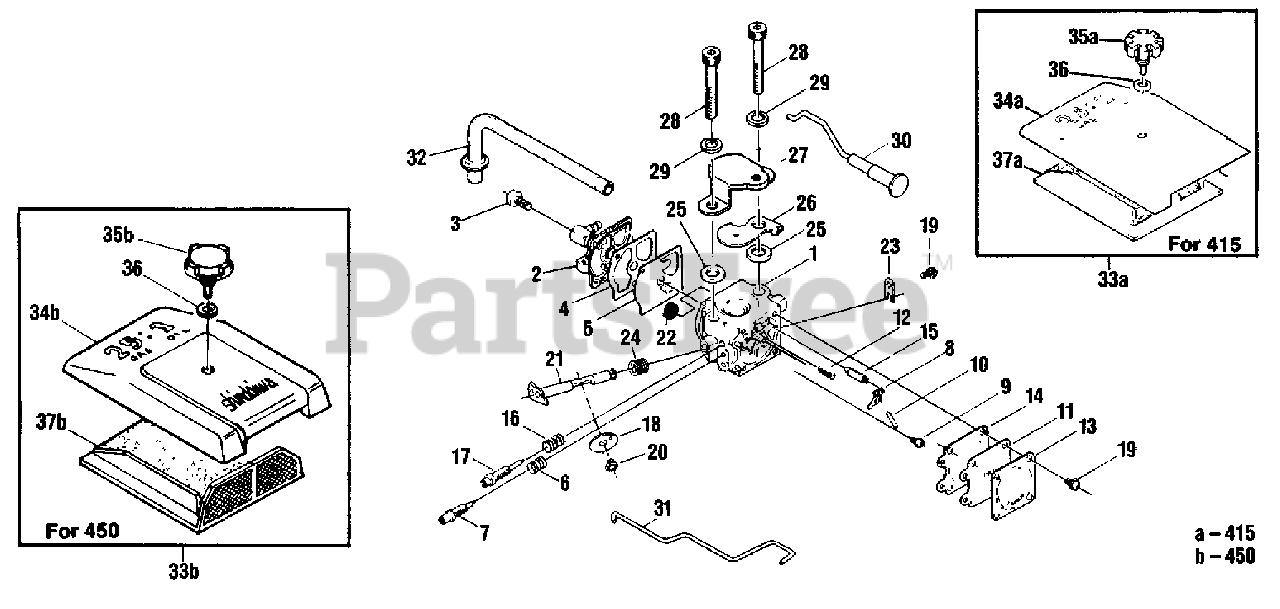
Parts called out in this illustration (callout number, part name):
1	BASE, PURGE
2	PUMP COVER ASSY
3	SCREW, PUMP COVER
4	GASKET, PUMP
5	DIAPHRAGM, PUMP
6	SPRING
7	NEEDLE - LOW SPEED
8	LEVER, METERING
9	SCREW, METERING LEVER PIN
10	PIN, METERING LEVER
11	DIAPHRAGM, METERING
12	SPRING, METERING LEVER
13	DIAPHRAGM, METERING
14	GASKET, METERING
15	VALVE, INLET NEEDLE
16	SPRING
17	NEEDLE - HIGH SPEED
18	VALVE, THROTTLE
19	SCREW
20	SCREW
21	SHAFT
22	STRAINER
23	RING, RETAINING
24	SPRING, RETURN
25	WASHER
26	PLATE, SHUTTER
28	SCREW - 5X40
29	LOCKWASHER - 5
30	ROD, CHOKE
31	ROD, THROTTLE
32	PIPE - IMPULSE
33A	AIR FILTER COVER ASSY
33B	AIR FILTER COVER ASSY
34A	COVER, AIR FILTER
34B	COVER, AIR FILTER
35A	THUMBSCREW
35B	THUMBSCREW
36	O-RING
37A	FILTER, AIR - FLOCKED
37B	FILTER, AIR - FLOCKED
